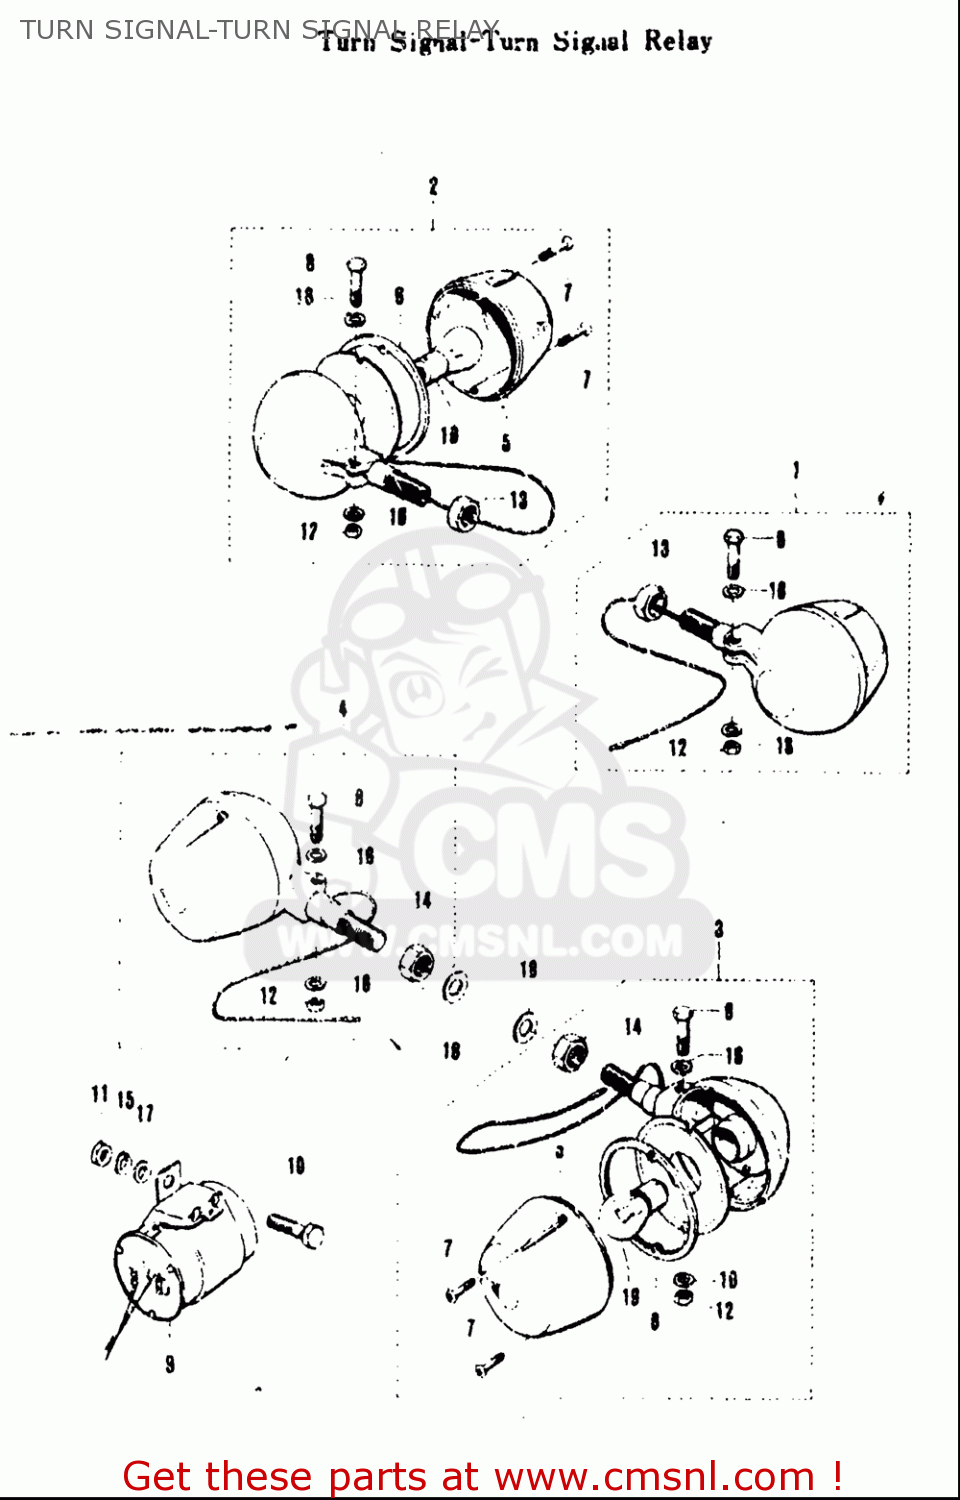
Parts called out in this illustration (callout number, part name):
5	LENS,TURNSIGNAL
6	GASKET,TURNSIGNAL LENS (NAS)
11	NUT
12	NUT
13	NUT
14	NUT
15	WASHER,LOCK
16	WASHER
17	WASHER
18	WASHER
